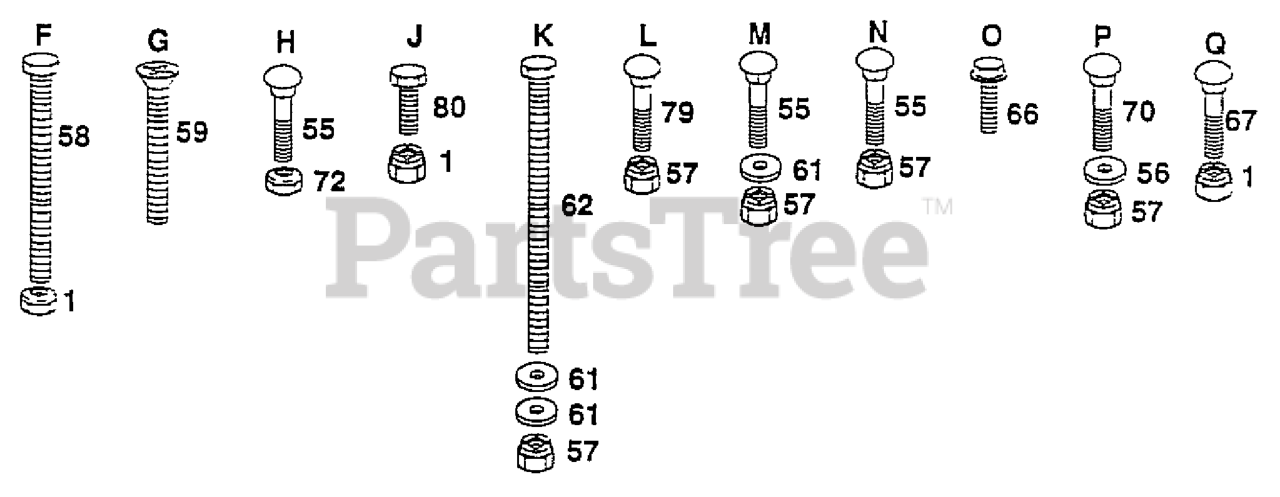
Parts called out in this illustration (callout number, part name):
1	LOCKNUT
55	RP BOLT 5/16-18 X3/4 ZN/YEL GR
56	WASHER
57	LOCKNUT
58	BOLT
61	WASHER M
62	Bolt, Hex -5/16-18 x 5
66	SCREW
67	Bolt, Carriage 3/8-16 x 3/4
70	BOLT.CARR.SQNK.5/16-18UNC.X3/4
79	BOLT.CARR.5/16-18X5/8.SHORT
80	BOLT
